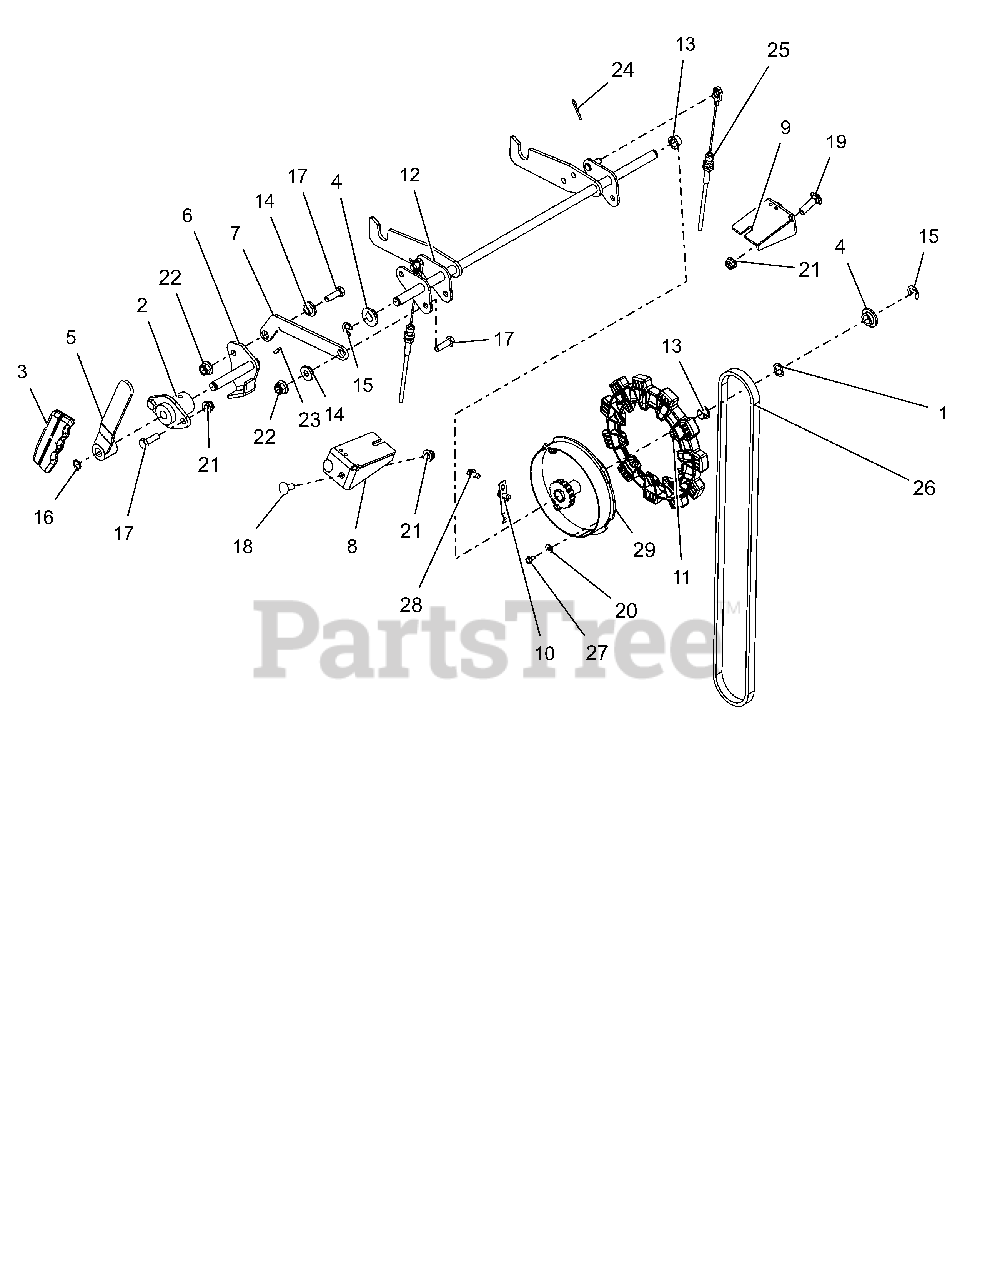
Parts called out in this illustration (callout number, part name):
1	WAVE WASHER .531X.781X.125FH
2	BUSHING, FLANGED
3	GRIP, PARKING BRAKE (YELLOW)
4	BSHG-FLG .515X.750X.310X1.120
5	WMT, PARKING BRAKE HANDLE
6	WMT, PARKING BRAKE ACTUATING
7	LINK, BRAKE INTERLOCK
8	BRKT, BRAKE CABLE MTG
9	BRKT, LH CABLE MTG
10	ARM, HOC DETENT
11	WHEEL, HOC
12	WLDMT, PS BRAKE INTERLOCK
13	BUSHING, POLYLINER-.50 SPLIT
14	BSHG-FLG .32X.500X.344X.880
15	RG-RTNG-EXT .500X.042 (E)
16	RG-RTNG-EXT .500X.050 (SNAP)
17	@BLT-HEX .31-18X1.00 GR5 YWZC
18	@BLT-RDHDSQNK .31-18X.75 G5YZ
19	@BLT-RDHDSQNK .38-16X1.25 G5YZ
20	@WSHR-FL-STL.219X.50X.049 YWZC
21	@NUT-LK-NYL-FLG .31-18 YWZC
22	@NUT-LK-NYL-FLG .38-16 YWZC
23	KEY-WDRF .13X.63 HRD#5
24	PIN-HAIR INT .08X.18X1.18 YWZC
25	CABLE, PROSTANCE P.BRAKE
26	BELT, TIMING LONG
27	SCR-TAP 10-24X.375 PRE-COAT 80
28	SCR-TAP .25-20X.50 HWH TR YWZ
29	KIT, 48-60" HOC WLDMT W/DECAL
